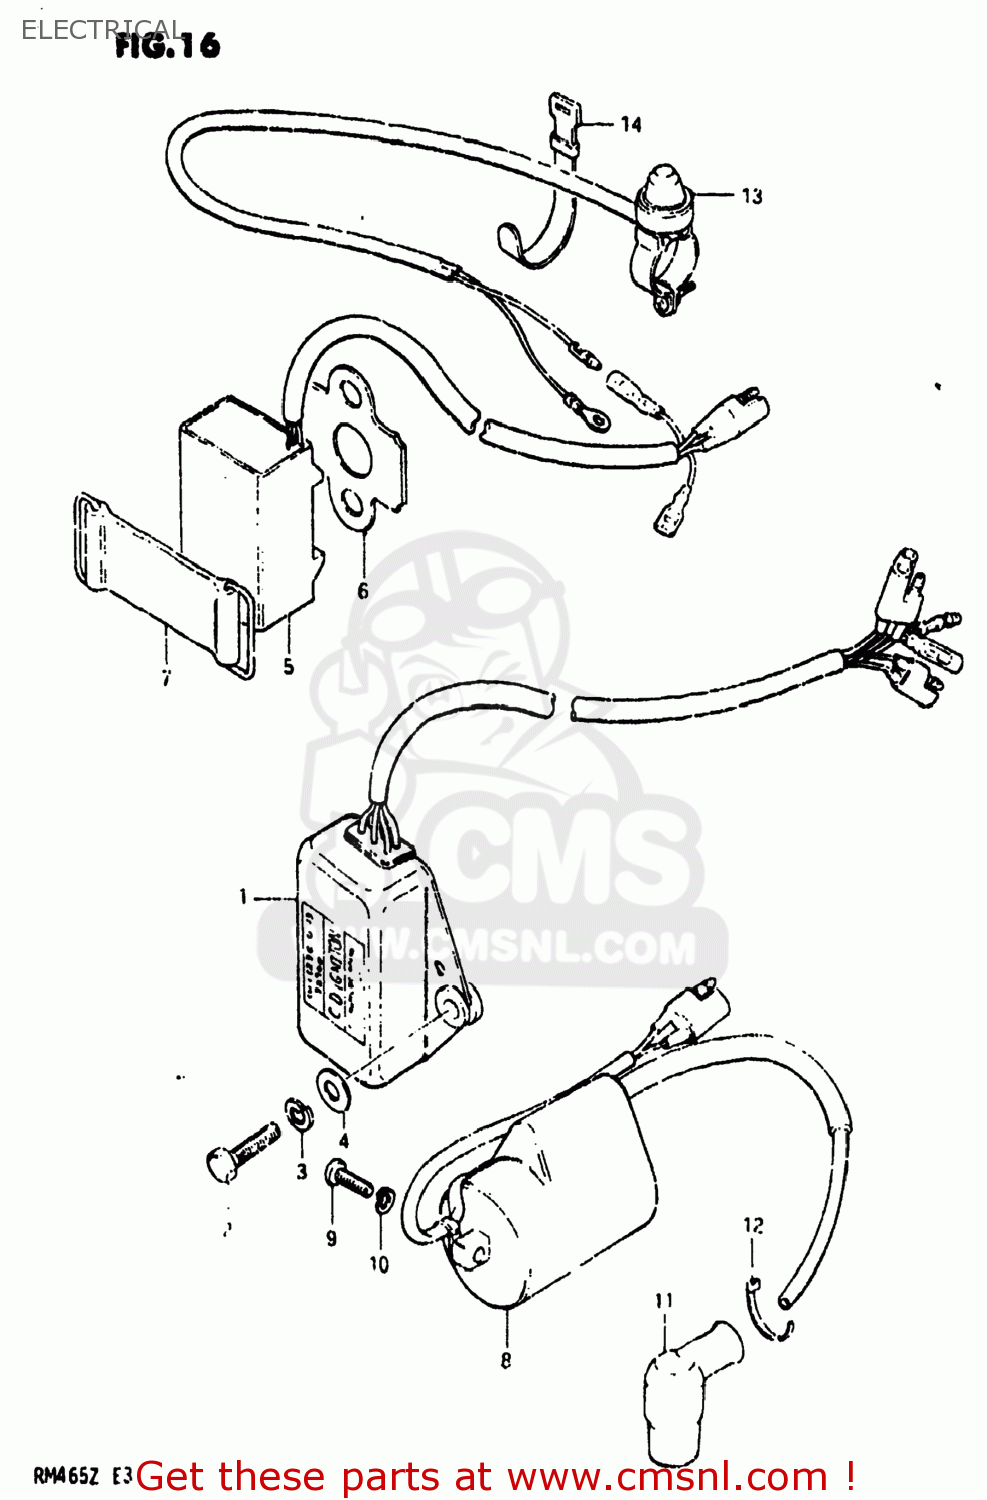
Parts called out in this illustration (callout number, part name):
1	CDI UNIT ASSEMBLY
2	BOLT
3	LOCK WASHER
4	WASHER(6.5X16X1.2)
5	CDI UNIT
6	PROTECTOR,CDI UNIT
7	BAND
8	COIL ASSY,IGNITION
9	SCREW 5X20
10	LOCK WASHER
11	CAP,SPARK PLUG
12	CLAMP
13	SWITCH ASSEMBLY
14	CLAMP(L:120)
